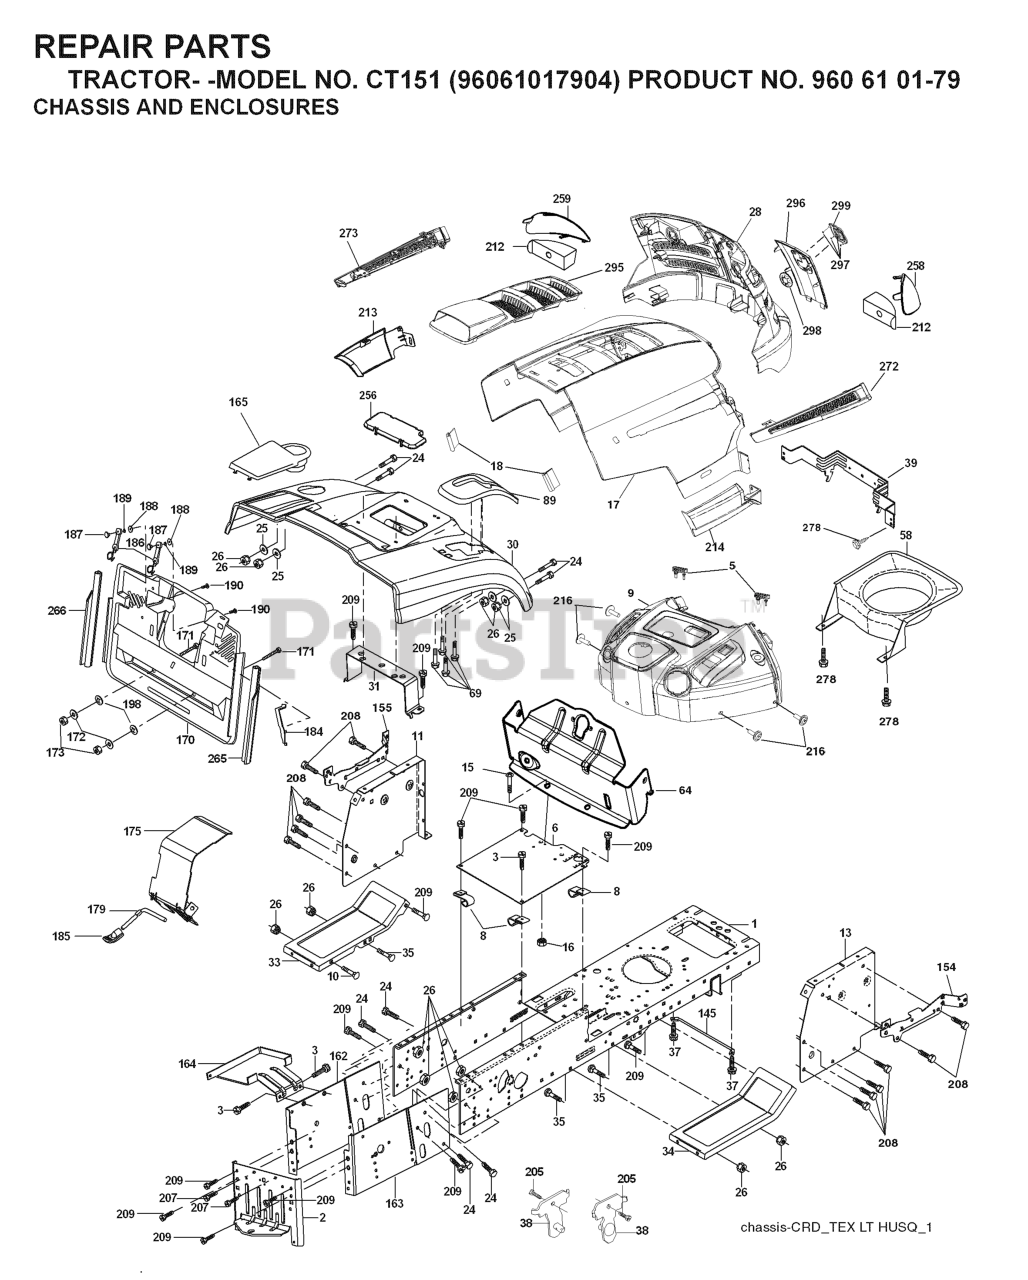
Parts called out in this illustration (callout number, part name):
2	DRAWBAR
3	SCREW 3/8-16X3/4
5	BUMPER DASH
6	PLATE
8	CLIP,INSULATOR
10	BOLT D
11	PANEL.DASH.LH.LTX
13	PANEL ASM, DASH RH
15	Screw, Machine, Truss Head 5/16-18 UNC x 3/4
16	NUT
17	HOOD
18	BUMPER.HOOD.TEX.HUSQVARNA
25	WASHER
26	NUT
28	RP GRILLE/LENS ASM.
30	CONSOLE.CRD.AUTO.GRY
31	BRACKET SUPPORT FENDER
33	FOOTREST PNT LH
34	FOOTREST PNT RH
37	Screw 5/16-18 x 1/2 Hex, Self Tapping 5/16-18 x 1/2
38	BRACKET ASM PIVOT MOWER REAR
39	BRACKET PIVOT
69	SCREW.HI-LO.CONSOLE
145	ROD.PIVOT.HOOD
162	BRACKET
163	BRACKET EXTEN CHASSIS RH CRD
165	RP.COVER.BATTERY.CRD.GREY
172	WASHER
175	DOOR TRAP
179	ROD PIVOT FBI
184	BRACKET.ACTUATOR.BAGGER.SRD
186	LATCH ASSY
187	WELDNUT
189	LOCKWASHER #10
190	SCREW
207	SCREW, 5/16-18 X 1/2
208	SCREW 3/8-16X1/2
209	SCREW, 3/8-16X3/4
212	INSERT REFLECTIVE
213	SKIRT SIDE LH
214	SKIRT SIDE RH
216	SCREW HEXWSHR 1/4-20X3/4
256	COVER FENDER CRD
258	LENS.HUSQVARNA LT.RH
259	LENS.HUSQVARNA LT.LH
265	SEALING
266	SEALING
272	VENT SIDE HOOD RH
273	VENT SIDE HOOD LH
278	SCREW
295	VENT TOP HOOD
296	TRIM
297	CLIP.RETAINER.TINNER.
298	NUT PUSH M
299	RP LOGO
